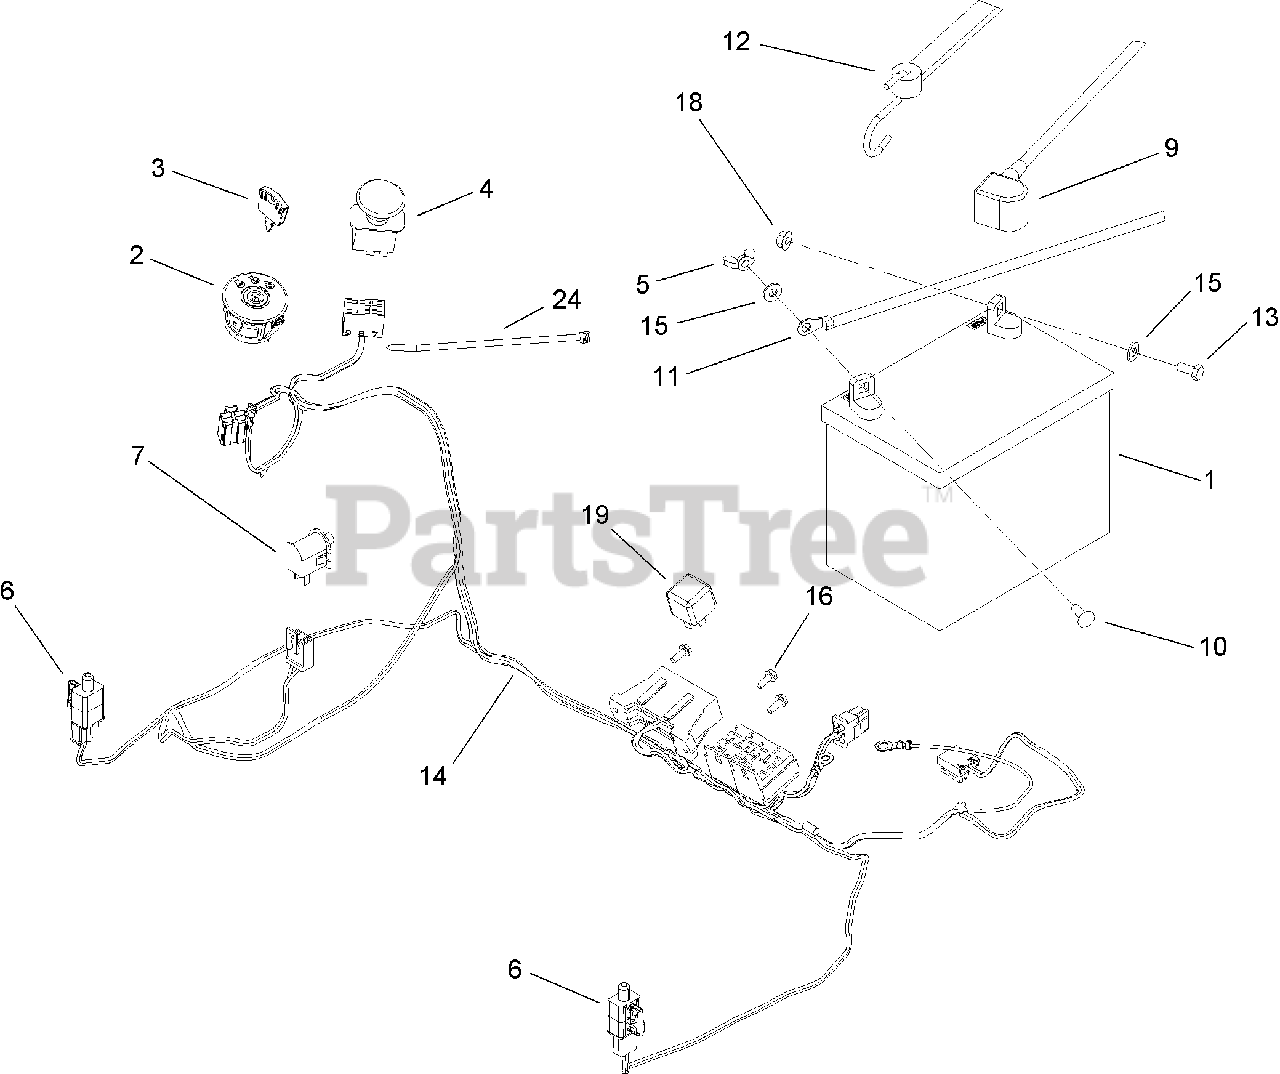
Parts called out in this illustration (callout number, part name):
1	BATTERY
2	SWITCH-IGNITION
4	SWITCH-PTO
6	SWITCH-SINGLE POLE NO
7	SWITCH-BAIL
9	CABLE-BATTERY, RED
10	SCREW-CARR
11	CABLE-BATTERY, BLACK
12	HOLDDOWN-BATTERY
13	SCREW-HH
14	HARNESS-WIRE
15	WASHER-FLAT
16	SCREW-TAPTITE
24	STRAP-TIE
